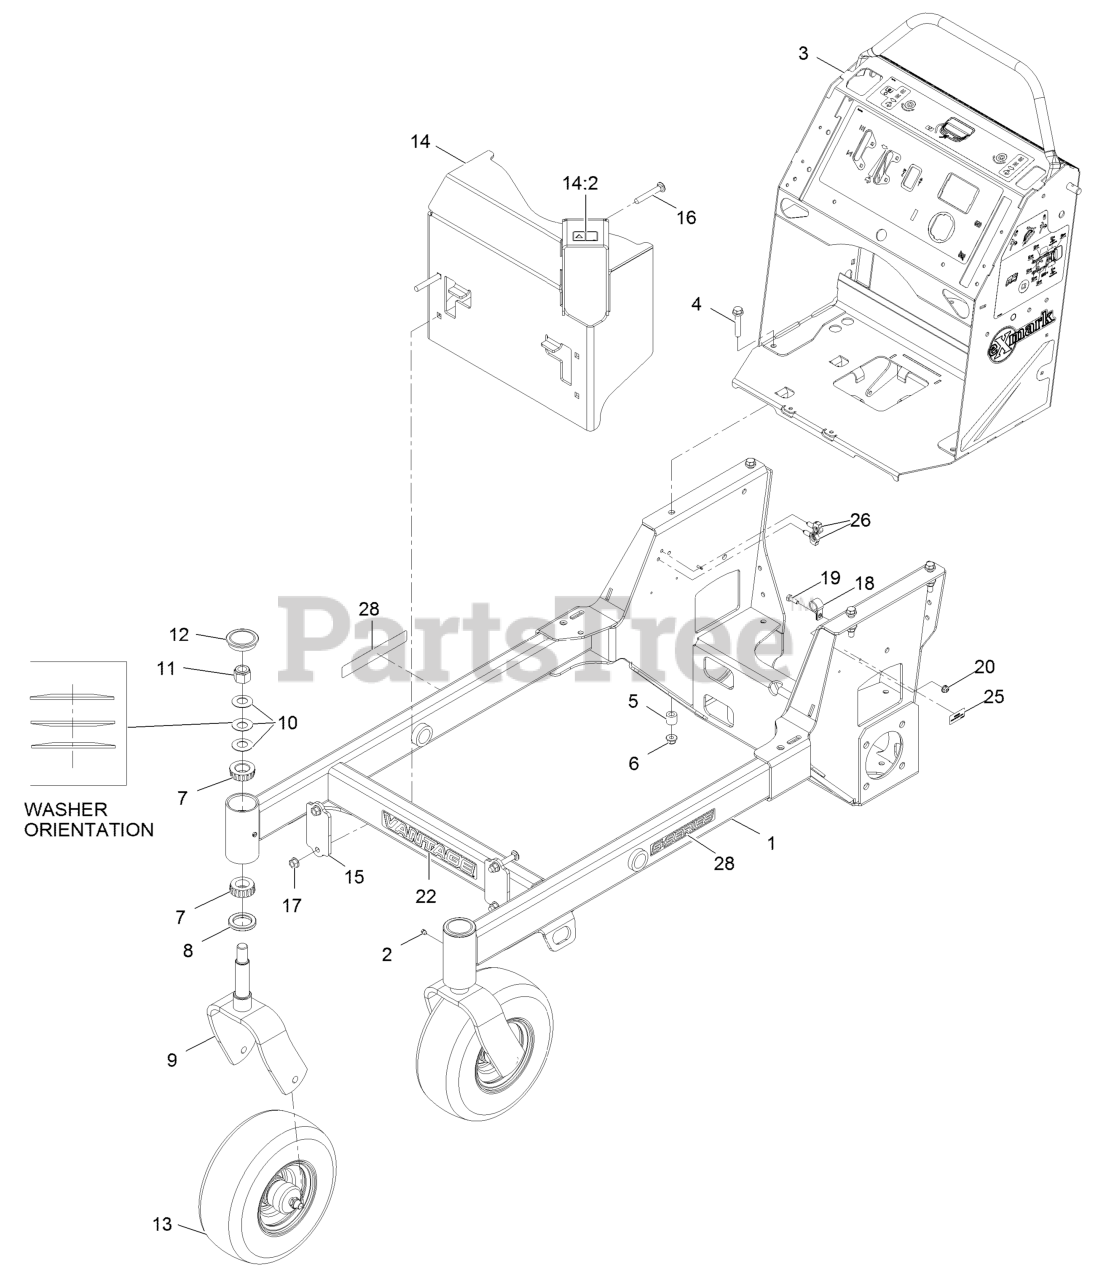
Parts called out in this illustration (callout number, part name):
1	FRAME ASM
3	CONTROL TOWER ASM
4	SCREW-HHF
6	NUT-HF, NI
7	Cone-Bearing Tapered Roller
8	SEAL-GREASE
9	FORK-CASTER
10	WASHER-BELLVILLE
11	NUT-LOCK, NI
12	CAP-GREASE
13	WHEEL/TIRE AND BEARING AS
14	MUFFLER GUARD ASM
14:2	DECAL-WARNING
15	BRACKET-MOUNTING, GUARD
16	SCREW-CARR
18	CLAMP-CABLE
19	SCREW-HH
22	DECAL-VANTAGE LOGO
25	Decal-Patent Ttco.Com
26	CLIP-HARNESS
28	DECAL-S-SERIES
